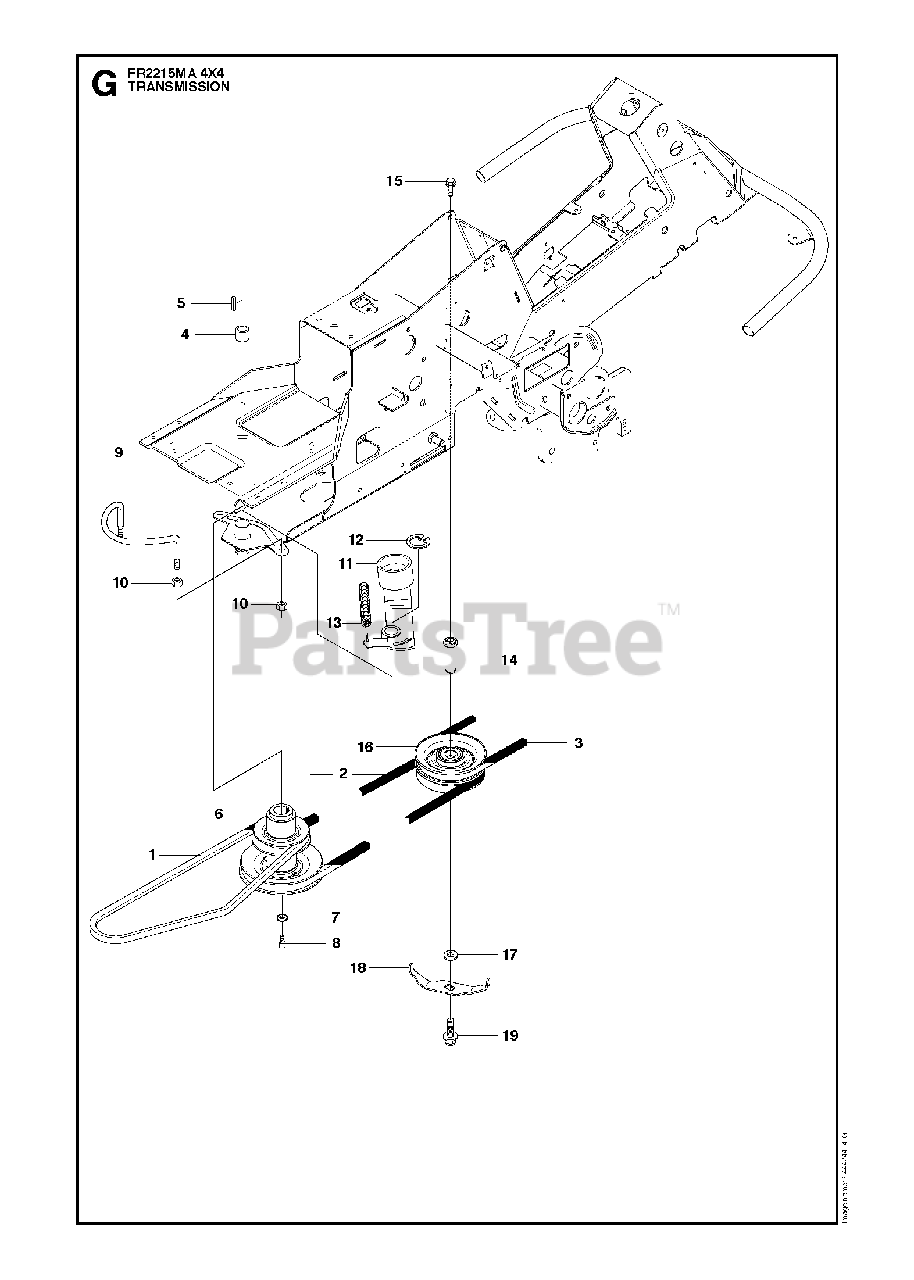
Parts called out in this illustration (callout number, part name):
1	BELT
2	BELT
9	BELT GUIDE
11	TENSIONER
12	RETAINING RING SGA 25
14	SHAFT
18	BELT GUIDE
19	BOLT
